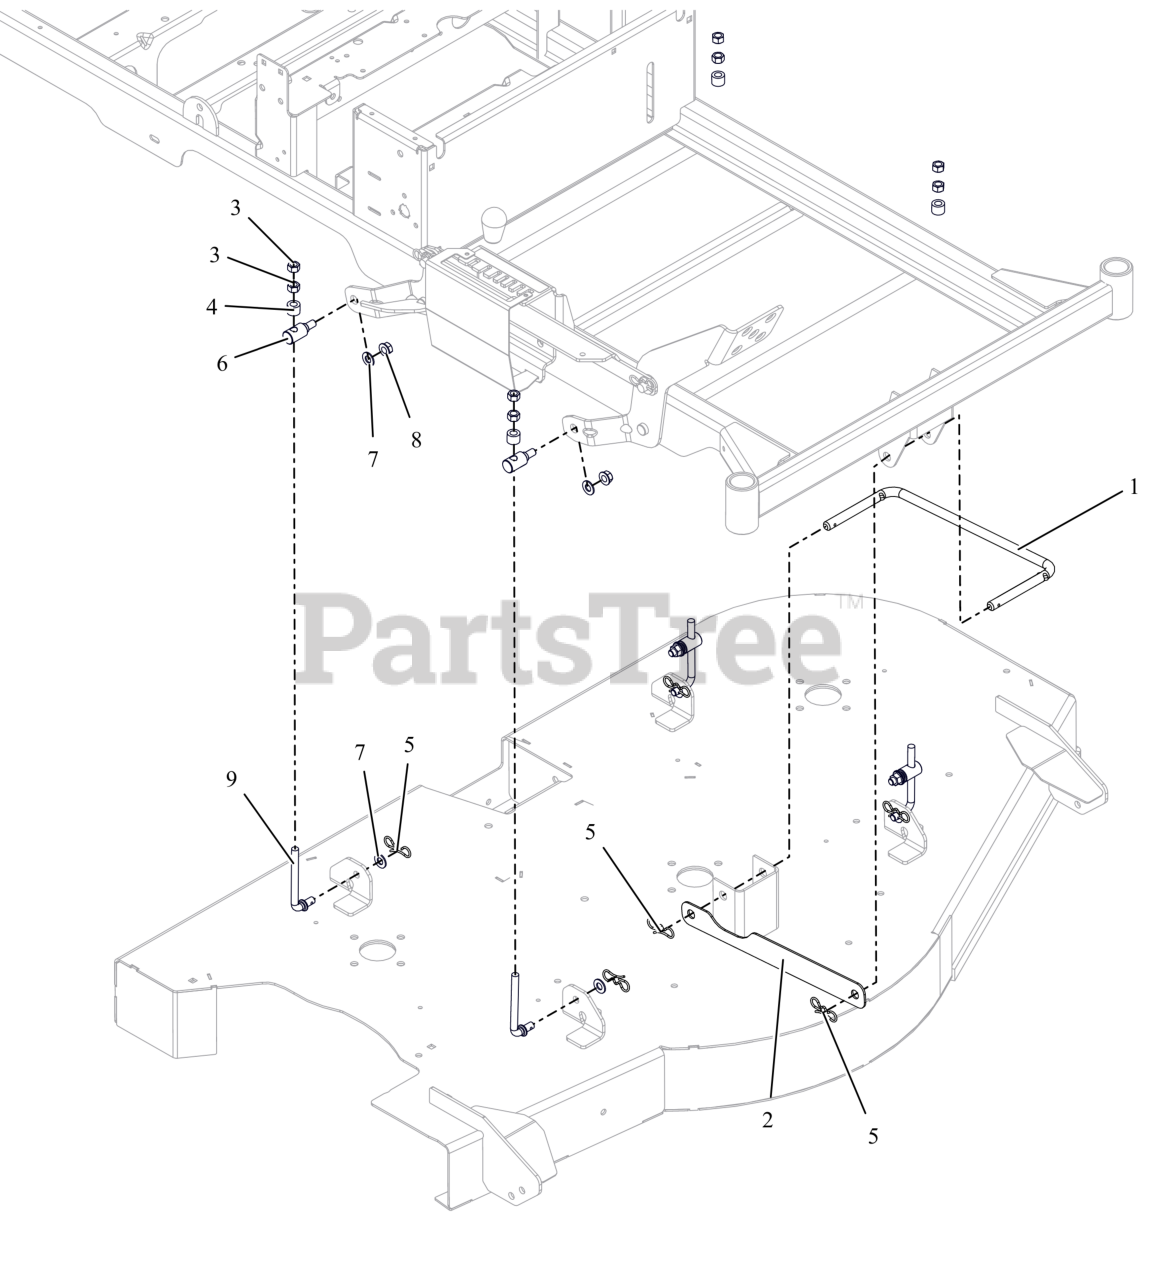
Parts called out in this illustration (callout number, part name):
1	WIREFORM, DRAG LINK
2	STRAP, DRAG LINK (ORANGE)
3	NUT-STD .375-16 G2 ZCC
4	BSHG-SLV .391X.688X.52 PM
5	PIN, BOWTIE .091X1.875 ZCC
6	TRUNNION, DECK ADJUSTER
7	WSHR,FLT .406X.812X.065 ZCC
8	NUT-LK-CTR-FLG .375-16 GF ZCC
9	WIREFORM, DECK ADJUSTMENT
